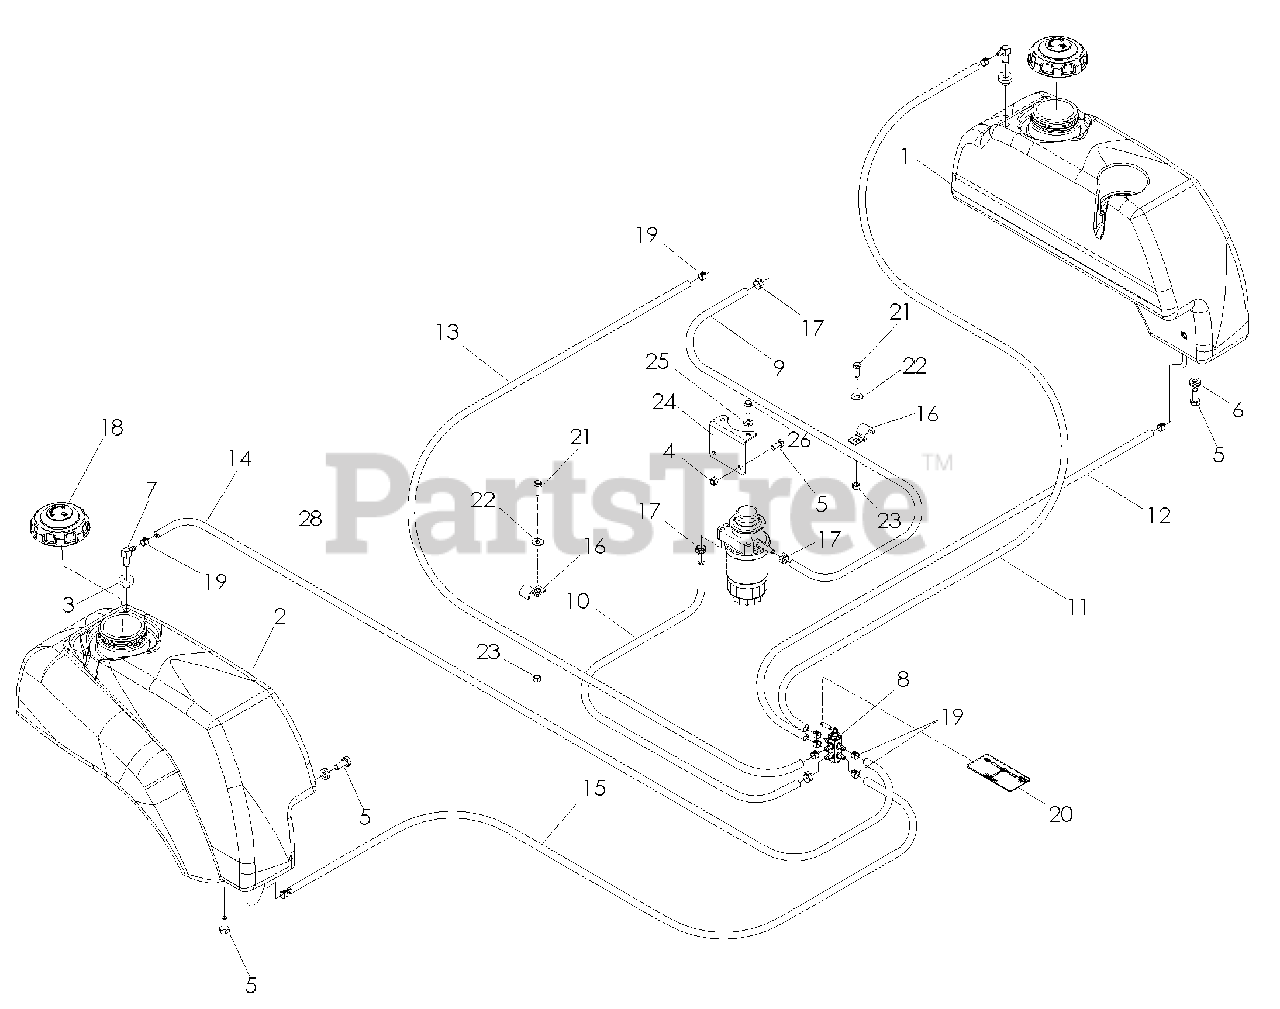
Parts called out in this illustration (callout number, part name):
1	FUEL TANK, LT
2	FUEL TANK, RT
4	NUT 5/16-18 HEX NYLOC
5	HCS 5/16-18 x 3/4
6	WASHER 5/16 SEALING
8	FUEL VALVE
18	CAP, DIESEL FUEL
19	CLAMP, HOSE
20	DECAL, FUEL VALVE
21	HCS 1/4-20 x 3/4
22	WASHER 1/4 FLAT STD
23	NUT 1/4-20 HEX NYLOC
24	BRACKET, MOUNTING
25	WASHER 5/16 SLOTTED LOCK
26	HCS M8-1.25 x 20mm
